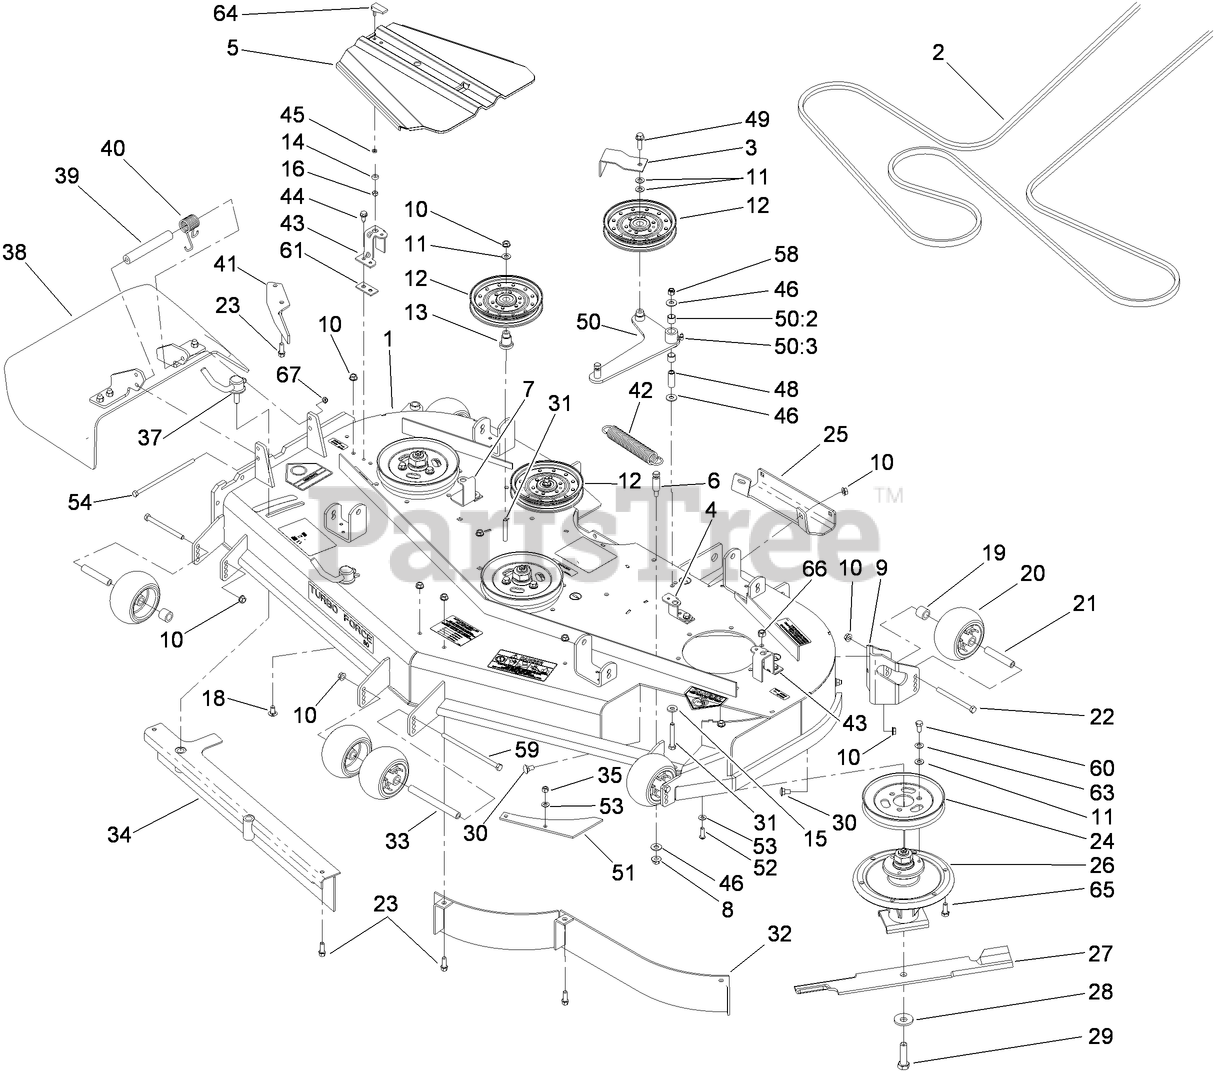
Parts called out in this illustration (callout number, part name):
1	DECK DECAL ASM
2	BELT-V
3	GUIDE-BELT
4	BRACKET-COVER, TALL
5	COVER-BELT
6	PIN-THREADED, SPRING ANCHOR
7	BRACKET-COVER
8	NUT-HF
9	MOUNT-WHEEL, LH
10	NUT-HHF, WHIZ
11	WASHER-FLAT
12	Idler-Flat
13	MOUNT-PULLEY
14	BUSHING-LATCH, SWELL
15	WASHER-BELLEVILLE
16	NUT-LOCK, HH
18	SCREW-CARR
19	TUBE-SPACER
20	ROLLER-SCALP, ANTI
21	TUBE-SPANNER
22	SCREW-HH
23	SCREW-HWH
24	Pulley
25	Plate-Skid
26	SPINDLE ASM
27	BLADE-HI FLOW
28	Washer-Blade Bolt, Heavy
29	SCREW-BLADE
30	SCREW-CARR
31	SCREW-HH
33	SPACER-WHEEL
35	NUT-LOCK, NI
37	LEVER ASM
38	RUBBER DEFLECTOR ASM
39	SPACER
40	SPRING-TORSION
41	BAFFLE-DISCHARGE
42	SPRING-EXTENSION
43	BRACKET-COVER
44	SCREW-HWHTF
45	WASHER
46	WASHER-FLAT
48	BUSHING
49	SCREW-HHF
50	DECK IDLER ARM ASM
50:2	SLEEVE-BEARING
50:3	FITTING-GREASE, 90 DEG
51	PLATE-TURBO
52	SCREW-HSBH
53	WASHER-SPRING
54	SCREW-HH
58	NUT-LOCK, NI
59	SCREW-HH
60	SCREW-HH
61	SPACER-COVER, BELT
63	WASHER-BELLEVILLE
64	HANDLE-LATCH, SWELL
65	SCREW-HH
66	NUT-LOCK, NI
67	NUT-LOCK, NI
